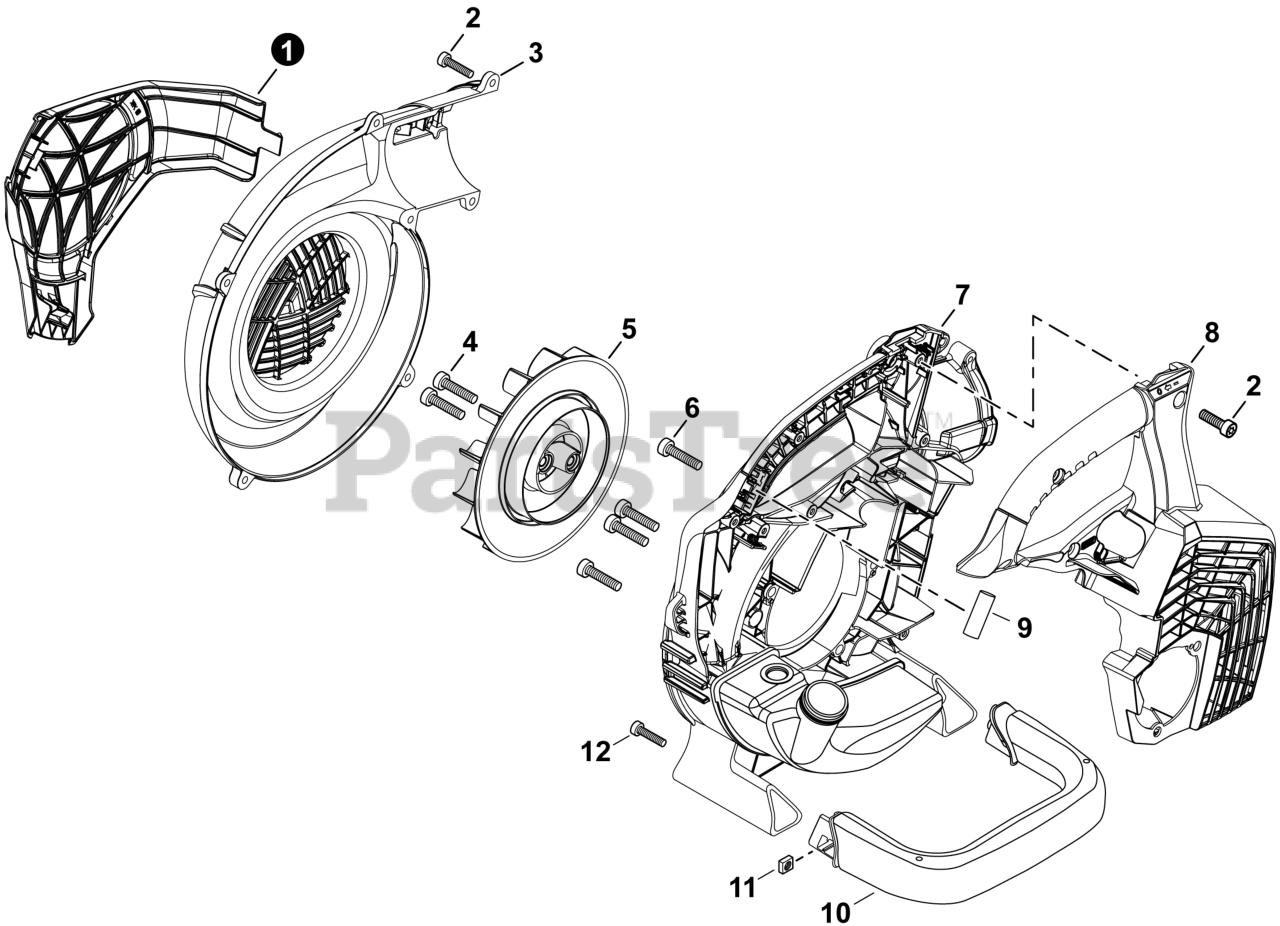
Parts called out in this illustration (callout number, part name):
1	GUARD, DEBRIS
2	BOLT, TORX 5x20
3	COVER, FAN CASE
4	BOLT, TORX 6x20
5	FAN, BLOWER
6	BOLT, TORX 5x16
7	FANCASE/FUEL TANK EB262 2020
8	COVER, ENGINE
10	HANDLE ASSY, REAR
12	BOLT, TORX 5x20
